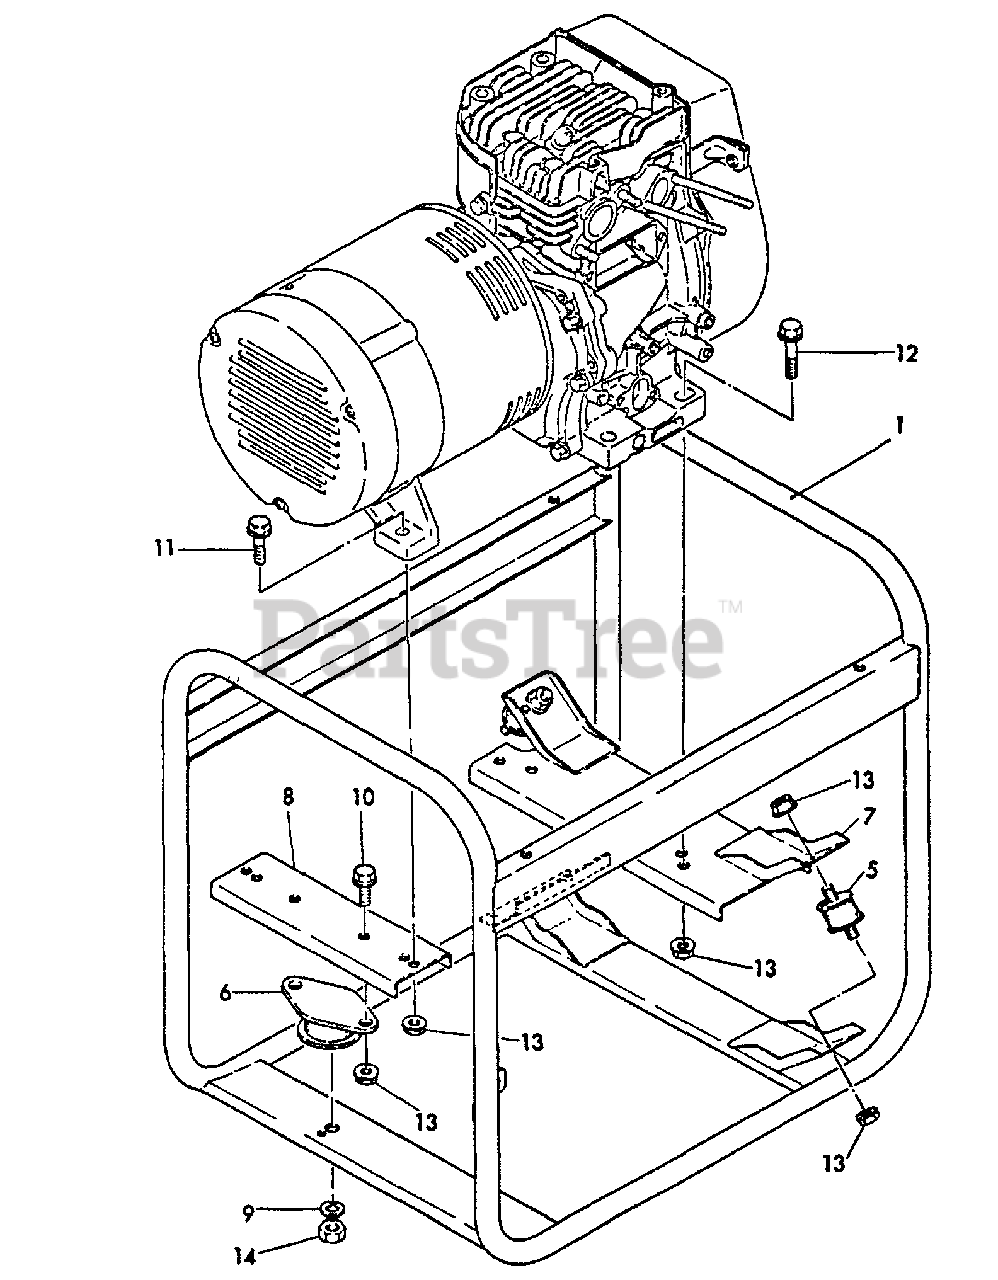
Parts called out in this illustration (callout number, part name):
1	FRAME ASSY
5	DAMPER, FRONT
6	DAMPER, REAR
7	STAY, DAMPER
8	STAY, REAR DAMPER
9	LOCKWASHER - 10
10	BOLT - 8X20 -- PLATED
11	BOLT - 8X30 -- PLATED
12	BOLT - 8X38 -- PLATED
13	NUT - 8
14	NUT - 10
